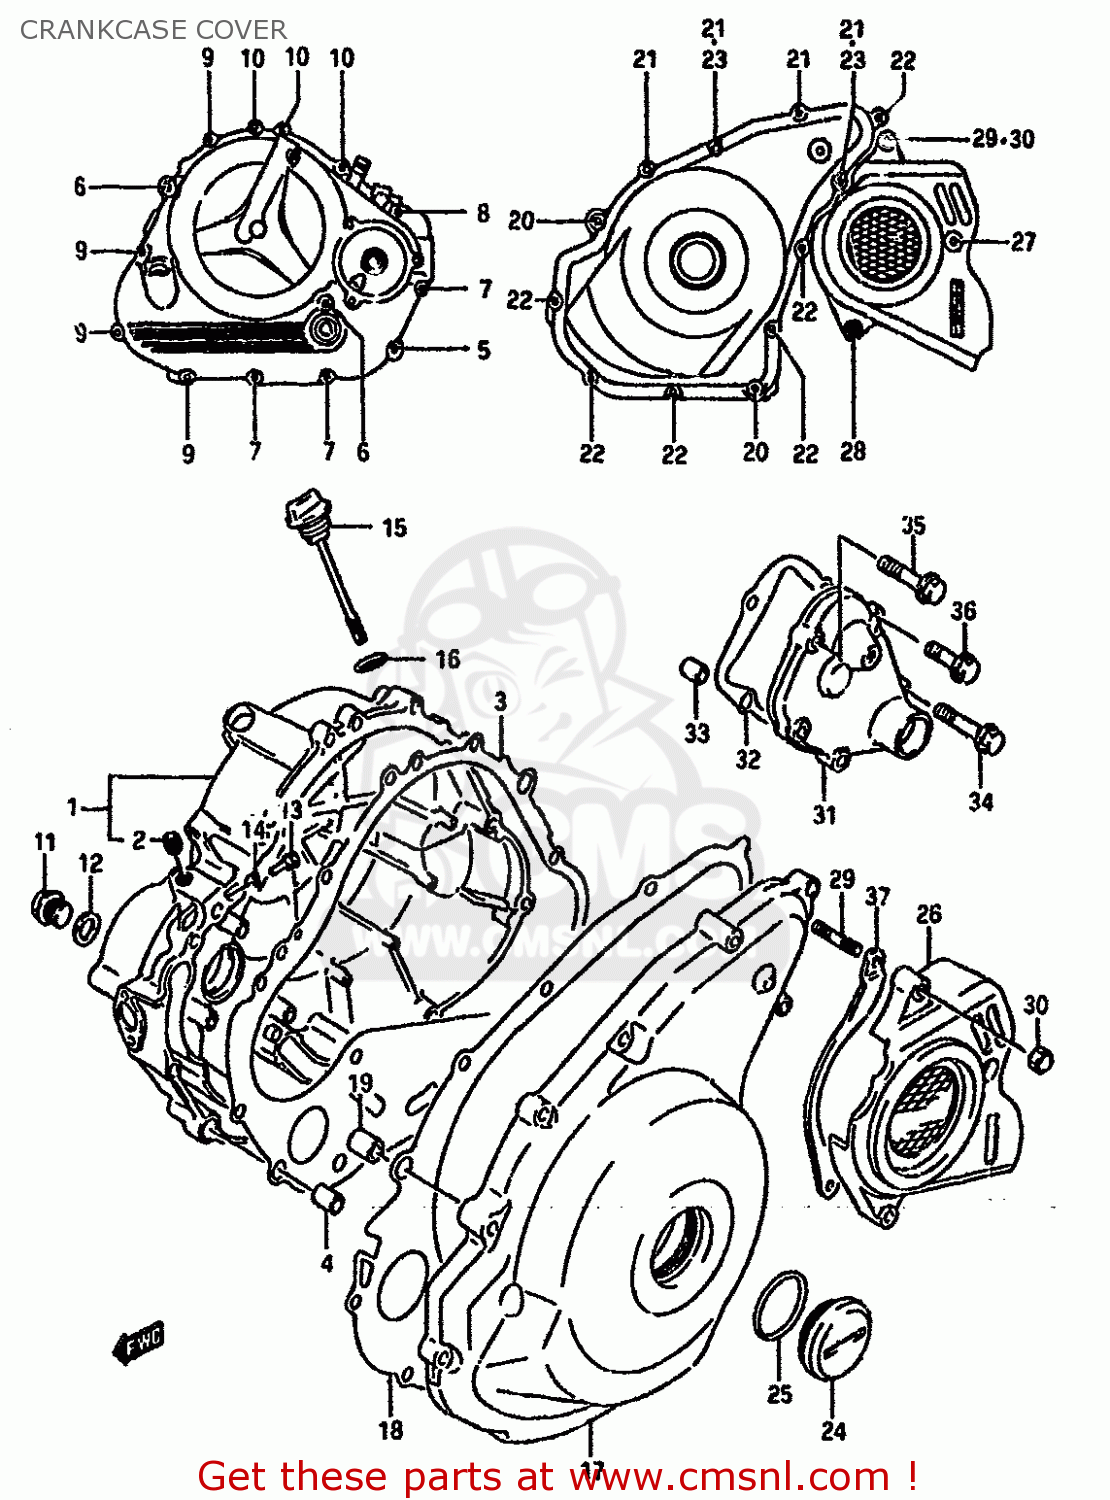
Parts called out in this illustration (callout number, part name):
1	COVER,CLUTCH (BLUE)
2	PLUG
3	GASKET,CLUTCH COVER (NA)
4	PIN
5	BOLT (6X60)
6	BOLT 6X50
7	BOLT
8	BOLT 6X40
9	BOLT 6X30
10	BOLT 6X25
11	PLUG(14X12)
12	GASKET(14X19.2X2) (NAS)
13	JET
14	O RING(D:1.2,ID:4)
15	GAUGE,OIL LEVEL
16	O RING(D:3.1,ID:16.8)
17	COVER,MAGNETO (BLUE)
18	GASKET,MAGNETO COVER (NA)
19	PIN
20	BOLT
21	BOLT 6X35
22	BOLT 6X25
23	GASKET(5.8X13X1.2) (NAS)
24	PLUG
25	O RING(D:3.1,ID:32.7)
26	COVER,ENGINE SPROCKET (BLUE)
27	BOLT 6X30
28	BOLT 6X25
29	BOLT,STUD
30	NUT
31	COVER,GEARSHIF
32	GASKET,GEAR SHIFT COVER
33	PIN
34	BOLT 6X30
35	BOLT 6X25
36	BOLT
37	PLATE,FR CHAIN GUIDE
